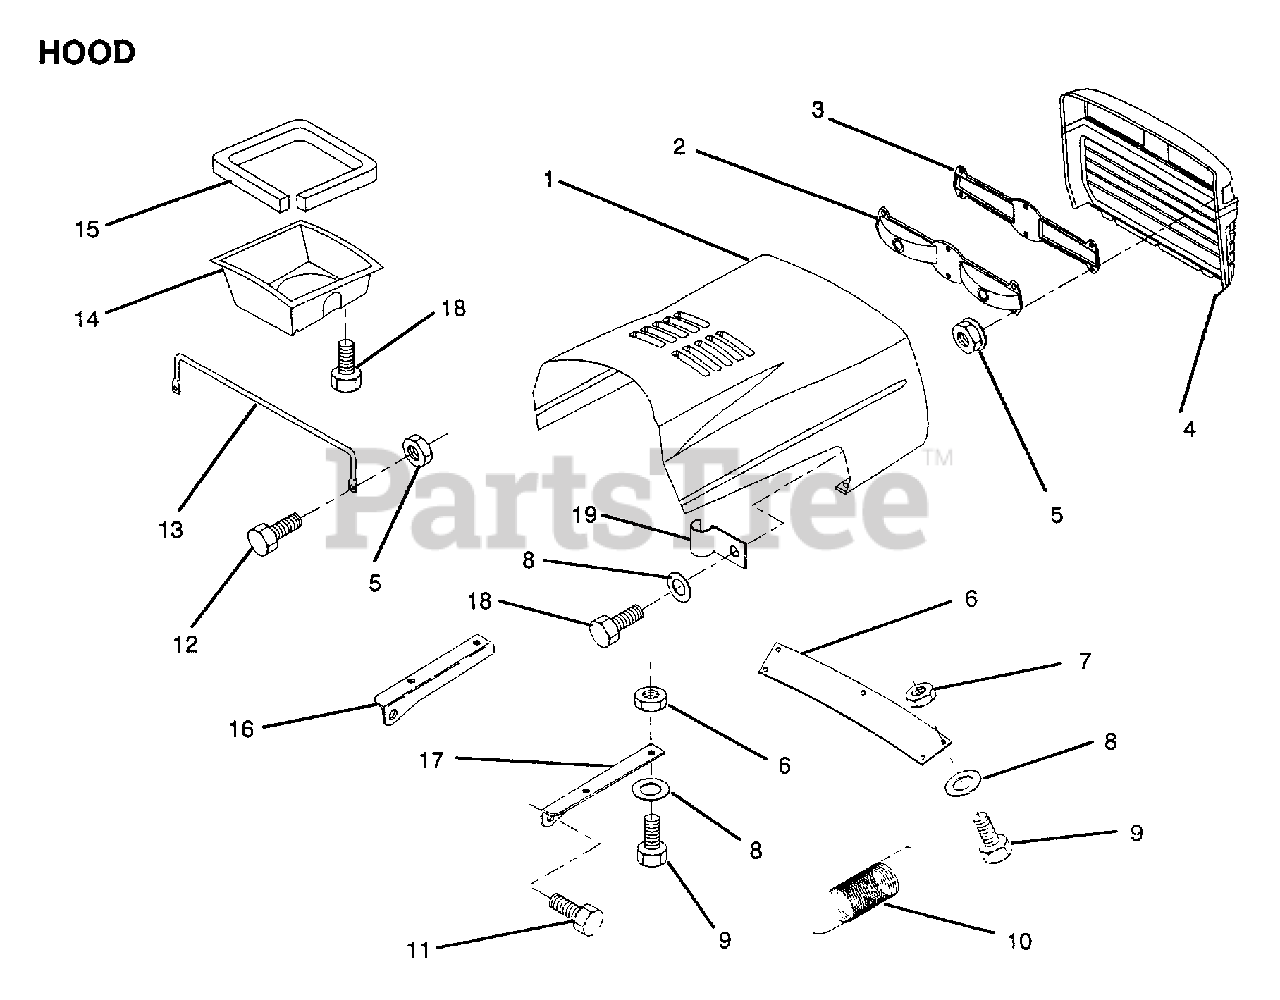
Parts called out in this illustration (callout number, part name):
5	NUT
6	"STRAP,GRILL T"
7	NUT
8	WASHER
9	BOLT
10	EXT SPRING
13	"BRACE,HOOD"
14	"DUCT,AIR"
15	FOAM STRIP LT
16	BRKT HOOD LH
17	BRKT HOOD RH
19	CLIP T
